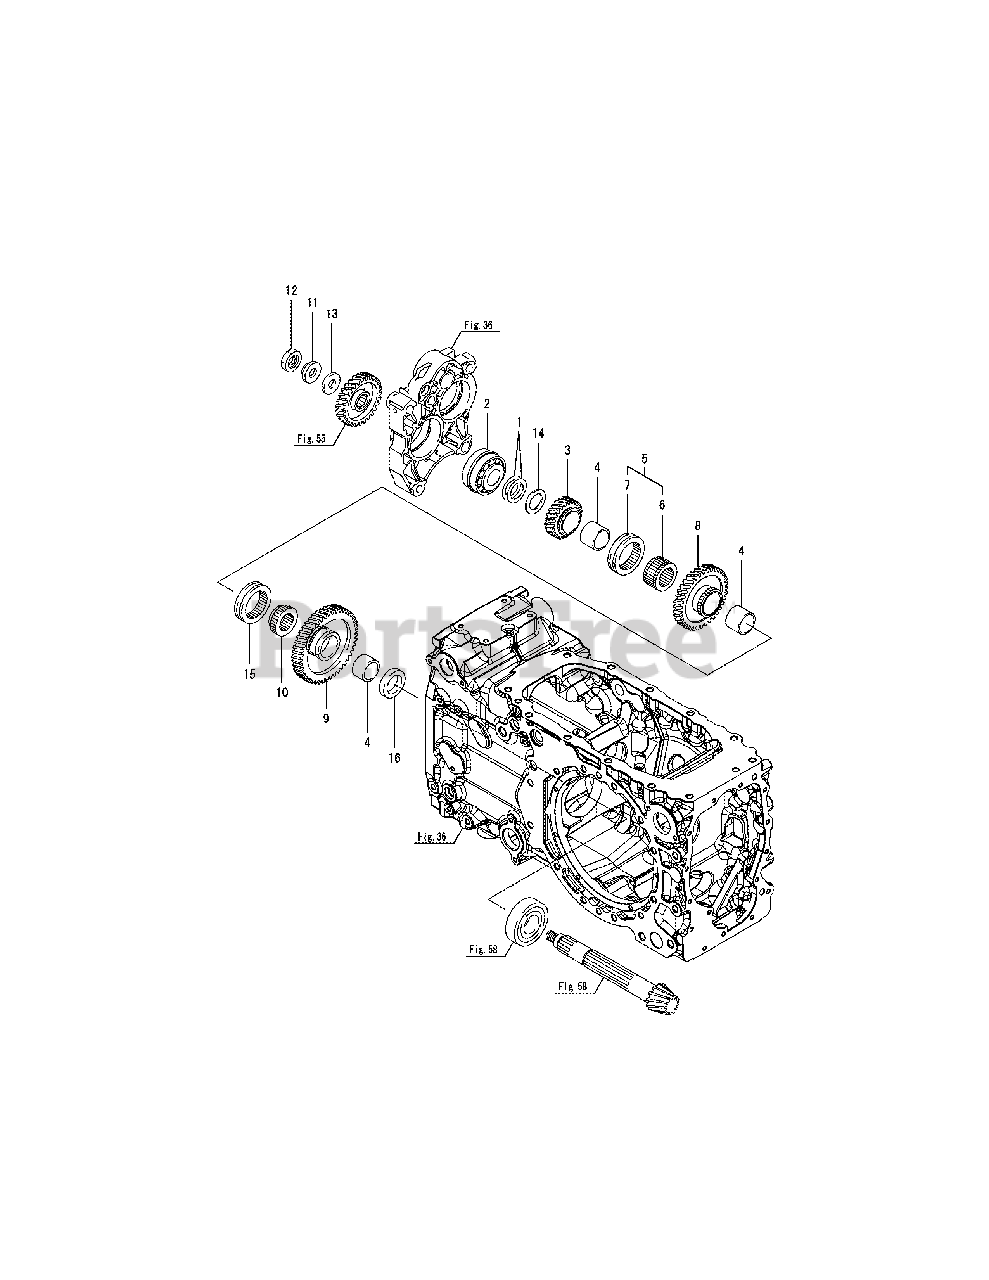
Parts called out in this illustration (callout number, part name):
2	BEARING 4T-30306 CMP
3	GEAR 19L, COUNTER
6	COLLAR, SPLINE
8	GEAR 41, COUNTER
9	GEAR 53, COUNTER
10	COLLAR, SPLINE B
13	WASHER 16X38X4.5
14	WASHER 30.3X45X3
